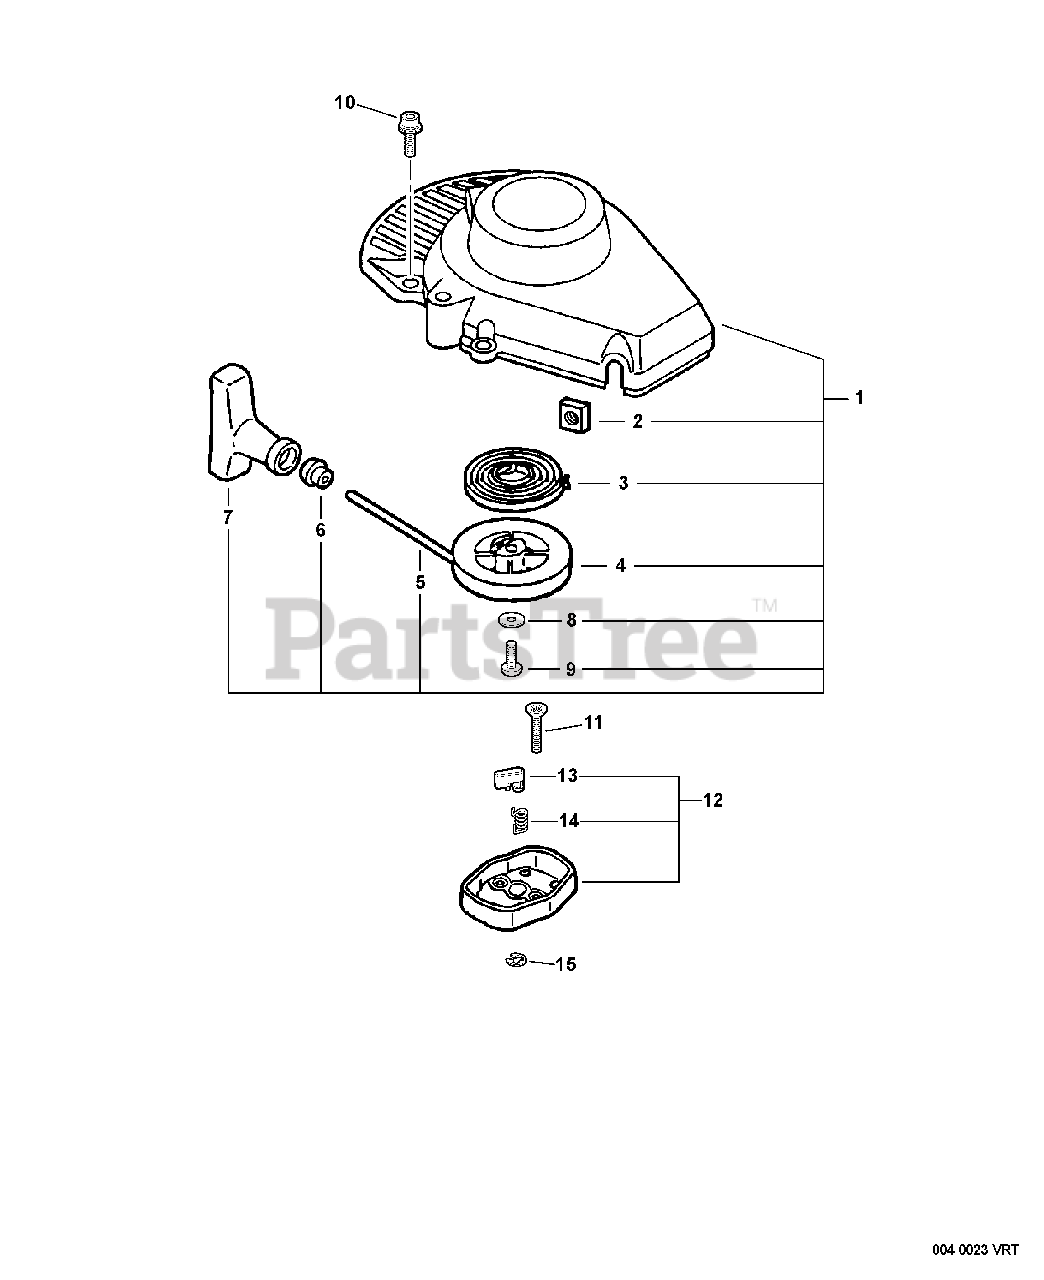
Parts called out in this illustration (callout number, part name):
1	STARTER, RECOIL
2	NUT M5
3	SPRING, RECOIL
4	REEL, ROPE
5	ROPE, STARTER 3×800
6	GUIDE, ROPE
7	GRIP, STARTER
8	WASHER
9	SCREW
10	BOLT 5×16
11	SCREW 6×14
12	PULLEY ASSY, STARTER
13	PAWL, STARTER
14	SPRING, RETURN
15	E-RING 4
